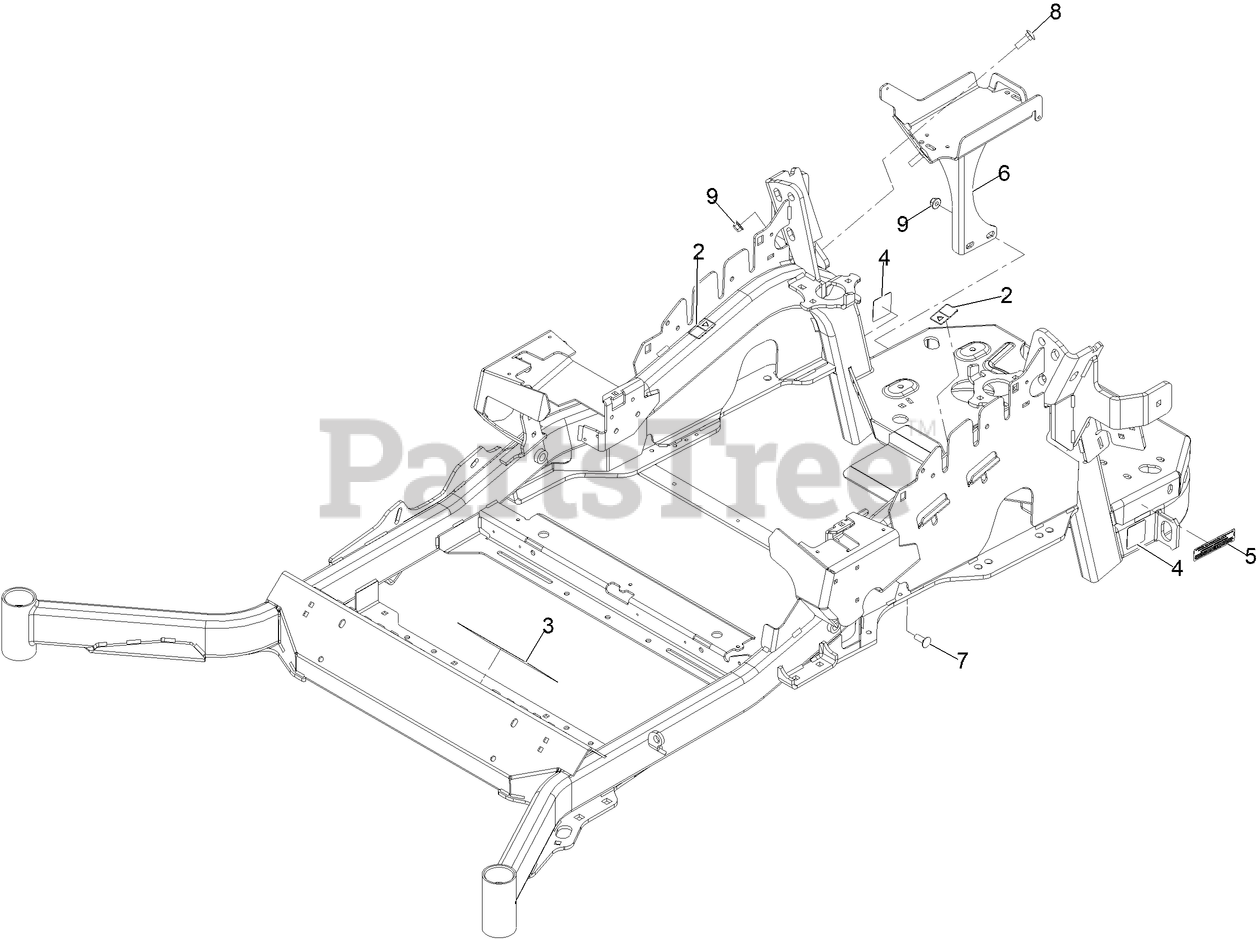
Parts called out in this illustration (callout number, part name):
2	DECAL-WARNING
3	DECAL-DANGER
4	DECAL-HAZARD, PINCHED FINGER
5	DECAL-ARRESTOR, SPARK
6	BATTERY MOUNT ASM
7	SCREW-CARR
8	BOLT-CARR
9	NUT-HF, NI
